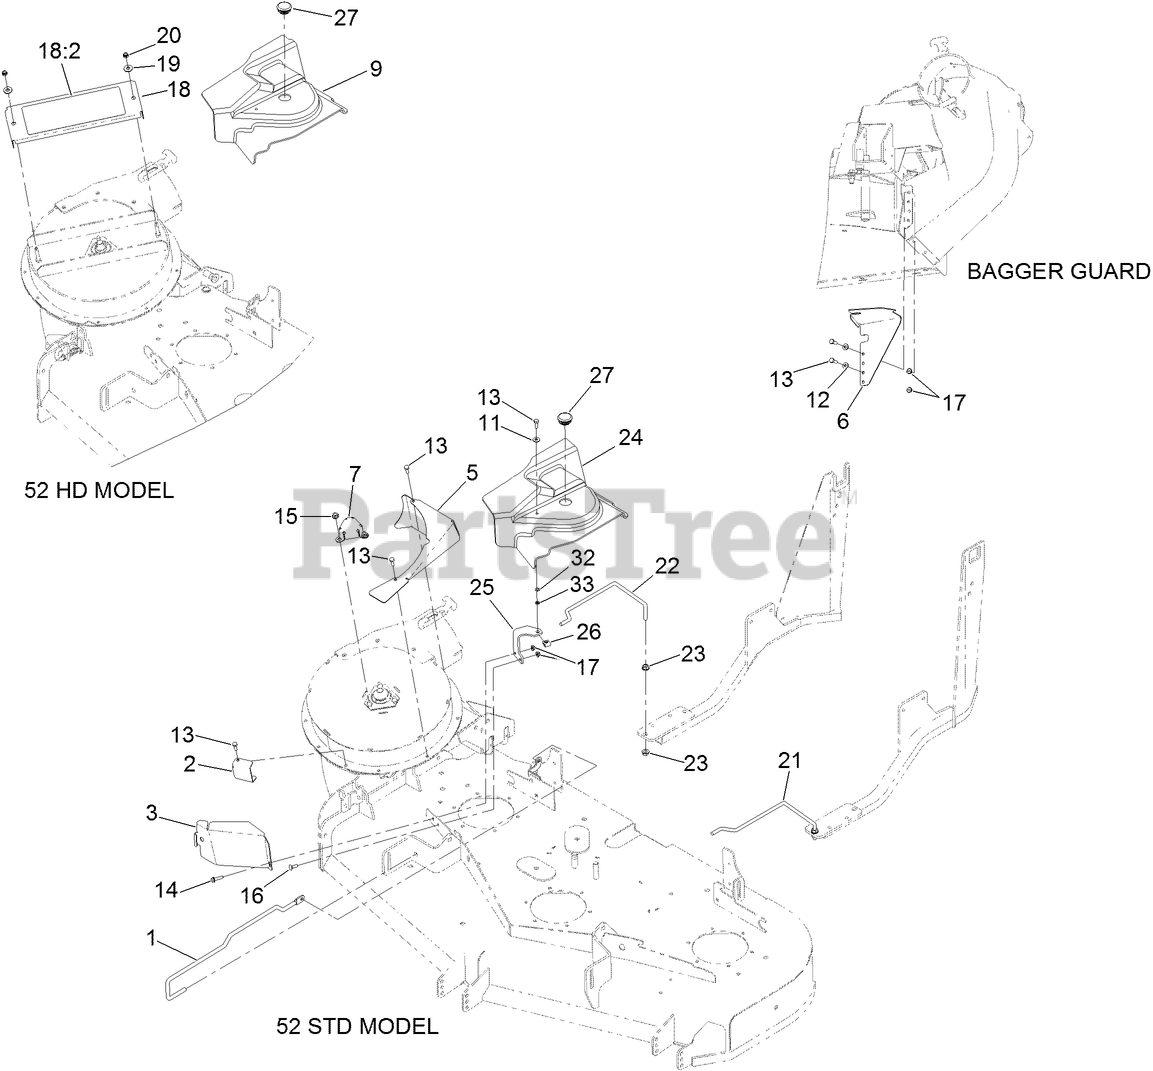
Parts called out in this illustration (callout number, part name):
1	ROD-SUPPORT, LOWER
2	GUARD-FRONT, LEFT
3	GUARD-BAGGER
5	GUARD-TOP
6	GUARD-BAGGER
7	COVER-NUT
9	BELT-COVER
11	WASHER-FLAT
12	WASHER-FLAT
13	SCREW-HH
14	SCREW-HHF
15	NUT-HF
16	BOLT-CARR
17	NUT-HF
18	COVER-BEARING
18:2	DECAL-DANGER
19	WASHER-FLAT
20	NUT-LOCK, NI
21	ROD-SUPPORT, REAR (LH)
22	ROD-SUPPORT, REAR (RH)
23	NUT-HHF, WHIZ
24	BELT COVER
25	BRACKET-COVER, BELT
26	NUT-SPEED
27	PLUG-PLASTIC
32	WASHER-FLAT
33	NUT-RETAINER
